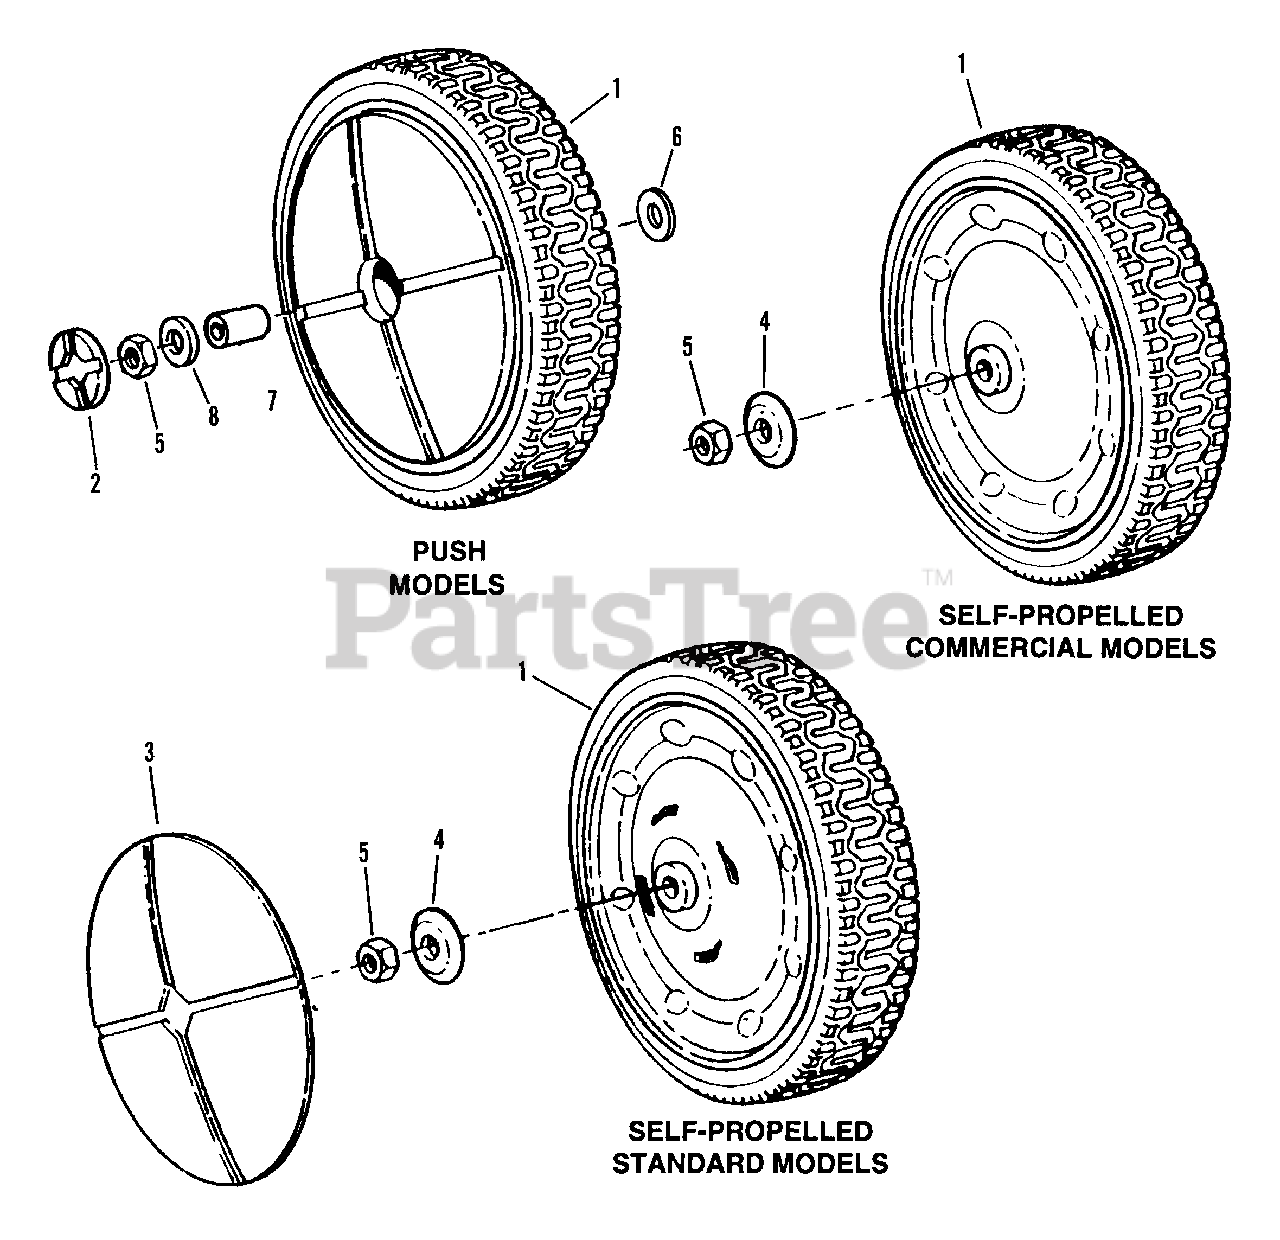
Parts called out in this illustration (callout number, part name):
1	WHEEL, 9 x 2.00 Plastic Rim
2	PLUG, Wheel
3	COVER, Wheel
4	HUB CAP
5	NUT, 5/16-18 Hex Center Lock
6	WASHER, 7/16 Flat
7	BUSHING, Axle
8	WASHER, 7/16" ID x 1" OD SAE
